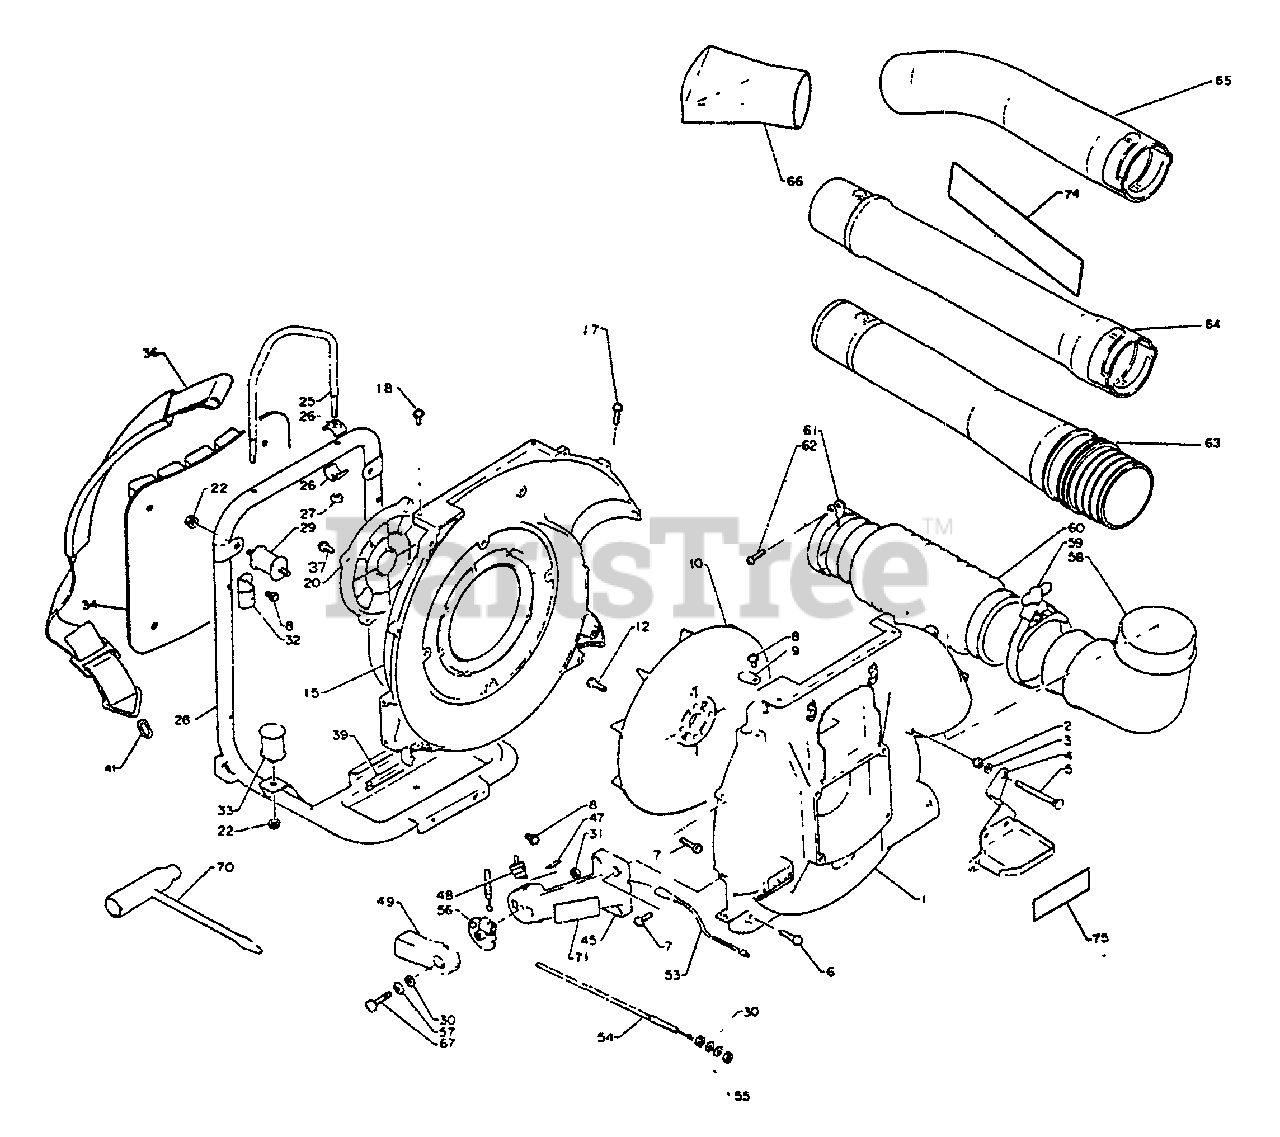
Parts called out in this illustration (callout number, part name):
1	COVER, FAN - OUTER
2	NUT - 5 -- CAP
3	WASHER - 5
4	BRACKET, MUFFLER COVER
5	BOLT, ELBOW
6	SCREW - 5X25
7	SCREW - 5X20
8	SCREW - 5X10
12	BOLT - 5X16
15	COVER, FAN - INNER -- ORANGE
17	SCREW - 6X20
18	SCREW - 6X15
20	GUARD, DEBRIS
22	NUT - 6 -- FLANGE
27	LOCKNUT - 6
28	FRAME, BACKPACK
30	WASHER - 6
31	LOCKNUT - 6
32	BRACKET, CUSHION
34	CUSHION, BACKPACK
36	BACKPACK STRAP ASSY
37	BOLT - 6X14
41	RING, STRAP
45	MOUNT, THROTTLE LEVER
47	LABEL - STOP
48	IGNITION SWITCH ASSY
49	TRIGGER, THROTTLE
54	CABLE, THROTTLE
58	TUBE, BLOWER - ELBOW
59	CLAMP
60	TUBE, BLOWER - FLEXIBLE
61	CLAMP KIT
62	SCREW - 5X25
63	TUBE, BLOWER - SWIVEL
64	BLOWER TUBE KIT - STRAIGHT
65	TUBE, BLOWER - CURVED
66	NOZZLE - FAN HEAD
67	SCREW - 6X25
70	T-WRENCH - 10X19mm
71	LABEL - CAUTION
74	LABEL - ECHO
75	LABEL - NOISE
